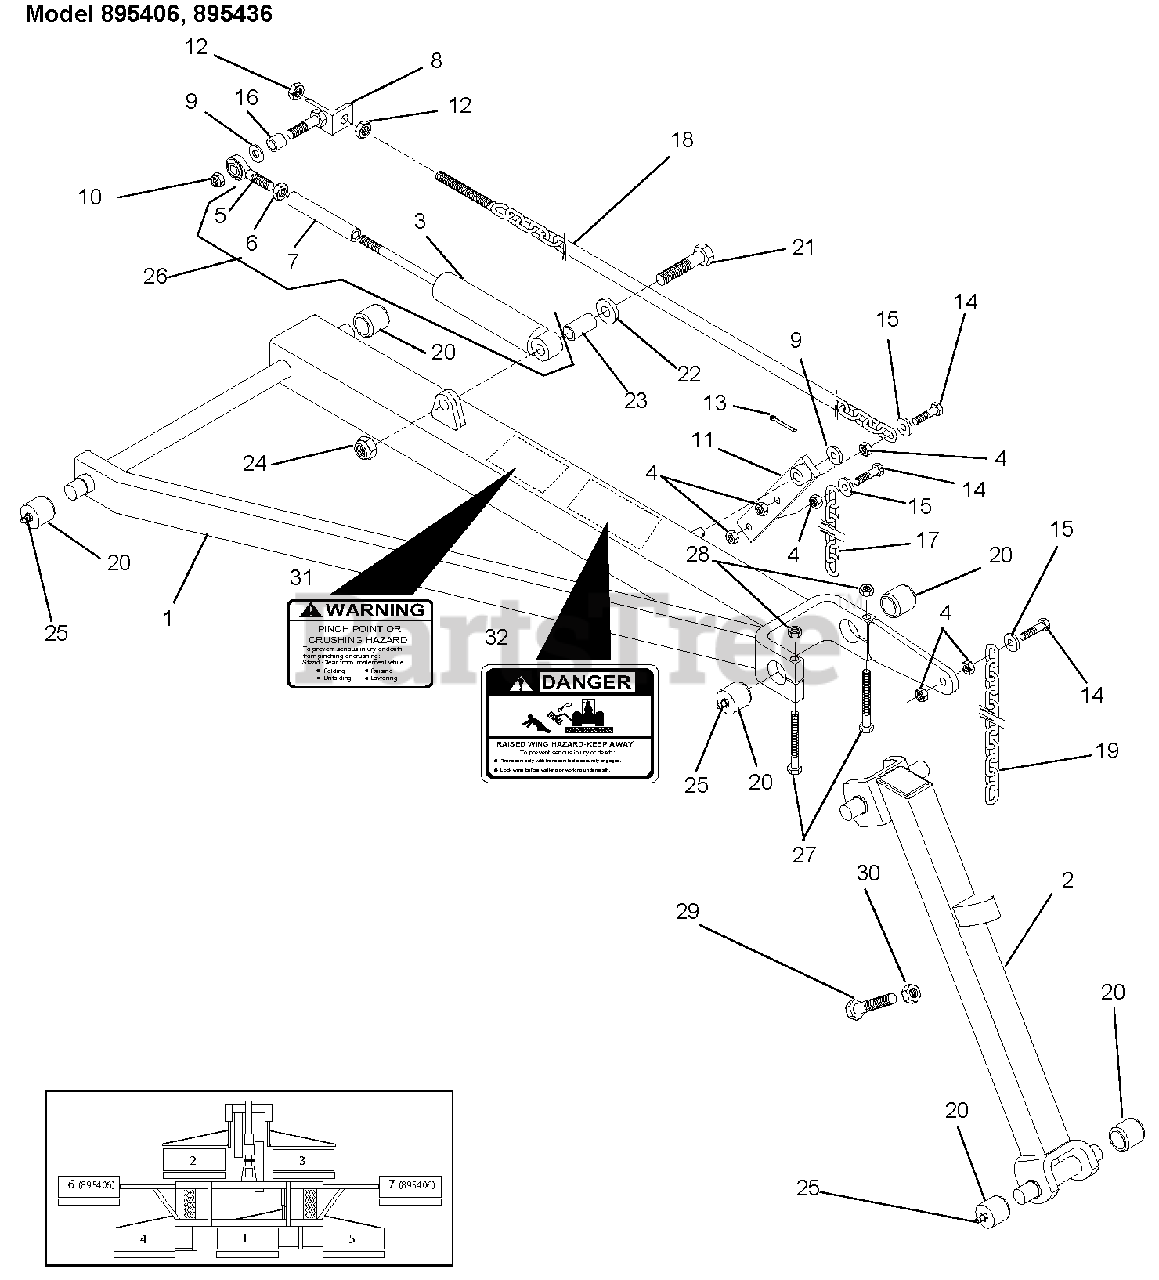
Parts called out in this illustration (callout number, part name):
1	Weldment, Inner Arm Left Hand
2	Weldment, Outer Lift Arm
3	Shock Absorber
4	Nut, Jam .375-16
5	Rod End, Male Right Hand .50-20
6	Nut, Jam .50-20 NF
7	Adapter, Damper Mounting
8	Weldment, Lug Damper
9	Washer, Flat .50 SAE
10	Nut, Nylock .50-13
11	Arm, Lift Chain
12	Nut, Jam .50-13
13	Pin, Cotter .156 x 1.0
14	Cap Screw, Hex Head .375-16 x 1.5
16	Damper, Bushing
17	Chain, Lift – Inside (#6 and #7)
18	Weldment, Chain Adjuster
19	Chain, Lift – Outside (#6 and #7)
20	Assembly, Bearing Cup
21	Cap Screw, Hex Head .625-11 x 3
22	Washer .625 SAE
23	Bushing, Damper
24	Nut, Nyloc .625-11
25	Fitting, Grease .25-20 Straight
26	Damper Assembly
27	Cap Screw, Hex Head .375-16 x 3
28	Nut, Hex Nyloc .375-16
29	Cap Screw, Hex Head .50-13 x 3.5
30	Nut, Hex .50
31	Decal, Warning
32	Decal, Danger
